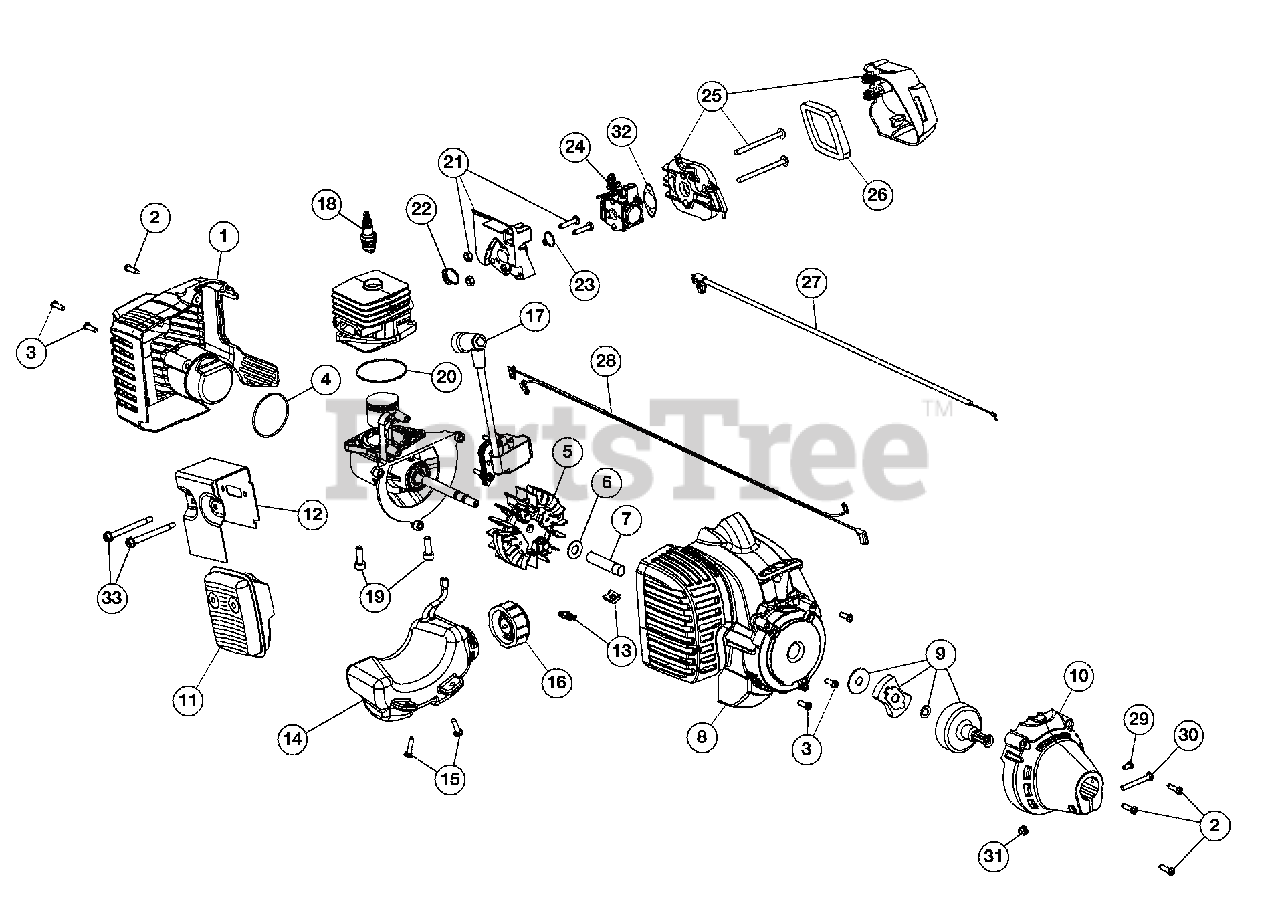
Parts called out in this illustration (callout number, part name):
1	Rear Cover Assembly (Incl. 2 & 3)
2	Cover Screw
3	Housing Screw
4	O-Ring
5	Flywheel Assembly
6	Washer
7	Spacer
8	Starter Housing (Incl. 3 & 13)
9	Clutch Assembly
10	Clutch Cover (Incl. 2)
11	Muffler Assembly (Incl. 12 & 33)
12	Muffler Gasket
13	U-shaped Nut
14	Fuel Tank Assembly (Incl. 15 & 16)
15	Tank Screw
16	Fuel Cap
17	Module Assembly
18	Spark Plug
19	Crankcase Bolt
20	Crankcase O-Ring
21	Insulator Assembly (Incl. 22 & 23)
22	Insulator O-Ring
23	Carburetor O-Ring
24	Carburetor
25	Air Cleaner Cover Assembly (Incl. 26)
26	Air Cleaner Filter
27	Throttle Cable
28	Lead Wires
29	Anti-rotation Screw
30	Clamp Screw
31	Clamp Nut
32	Air Cleaner Gasket
33	Muffler Screw
